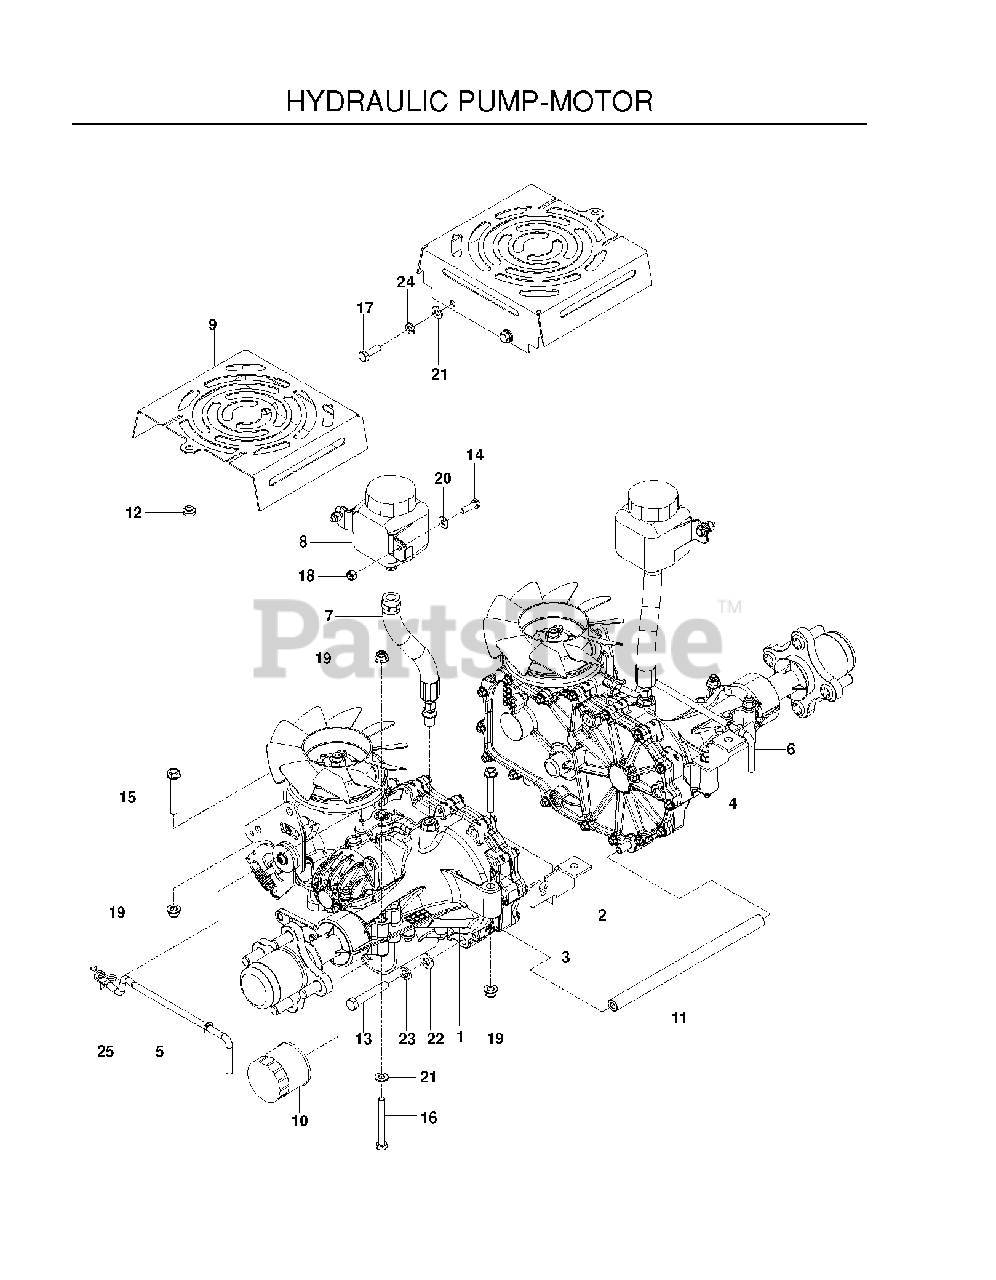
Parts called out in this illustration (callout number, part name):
5	LINKAGE, LEFT BYPASS
6	LINKAGE, RIGHT BYPASS
7	HOSE ASSY, EXPANSION
8	TANK, EXPANSION, 350ML
9	SHIELD, FAN, BLK
10	FILTER, ZT4800
11	TUBE, SPACER, 3400
12	GROMMET, BUMPER
13	HCS 3/8-16X2-1/4 LOC PATCH GR8
14	HCS 1/4-20X7/8 GR5
15	HHFS 5/16-18 X 2.25 GD 5
16	HCS 5/16C X 2-3/4
17	HCS 5/16C X 1
18	NUT 1/4-20 NYLOC
19	5/16-18 NYLOC FLANGE NUT
20	WASHER 1/4 SAE
21	FLAT WASHER 5/16 SAE
22	WASHER 3/8 SAE FLAT
23	SLW 3/8 STD
24	WASHER 5/16 LOCK
25	HAIRPIN #2
